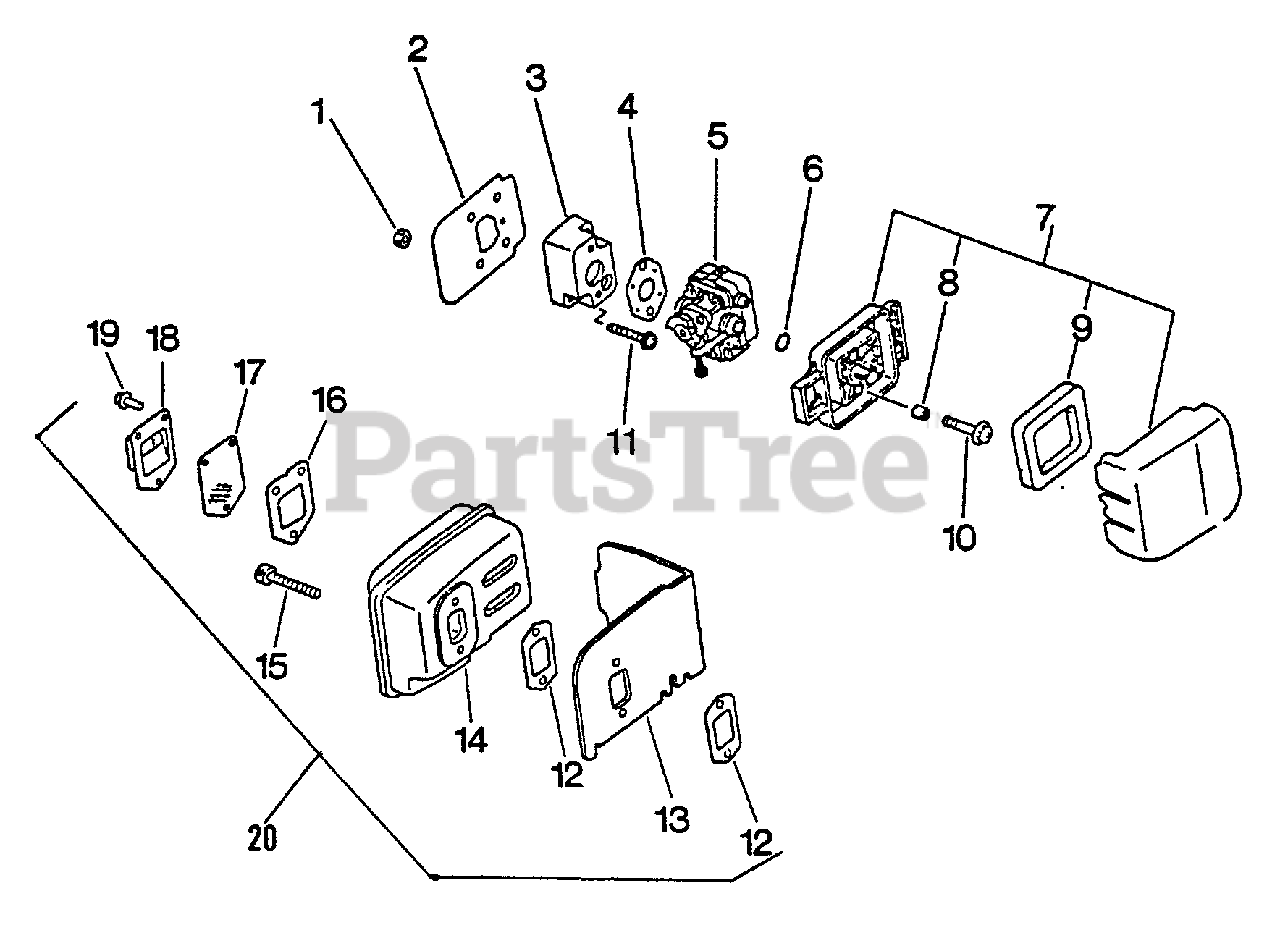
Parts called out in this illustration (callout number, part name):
2	SHIELD, INTAKE
3	INSULATOR, INTAKE
4	GASKET, INTAKE
5	CARBURETOR WYL-11
6	O-RING - 15
7	AIR CLEANER ASSY
8	SLEEVE
9	FILTER, AIR
10	SCREW - 5X64
11	SCREW - 5X22
12	GASKET, EXHAUST
13	COVER, EXHAUST
15	SCREW - 5X55
16	GASKET, EXHAUST
17	SCREEN, SPARK ARRESTOR
18	GUIDE, EXHAUST
19	SCREW - 4X10
20	MUFFLER ASSY
